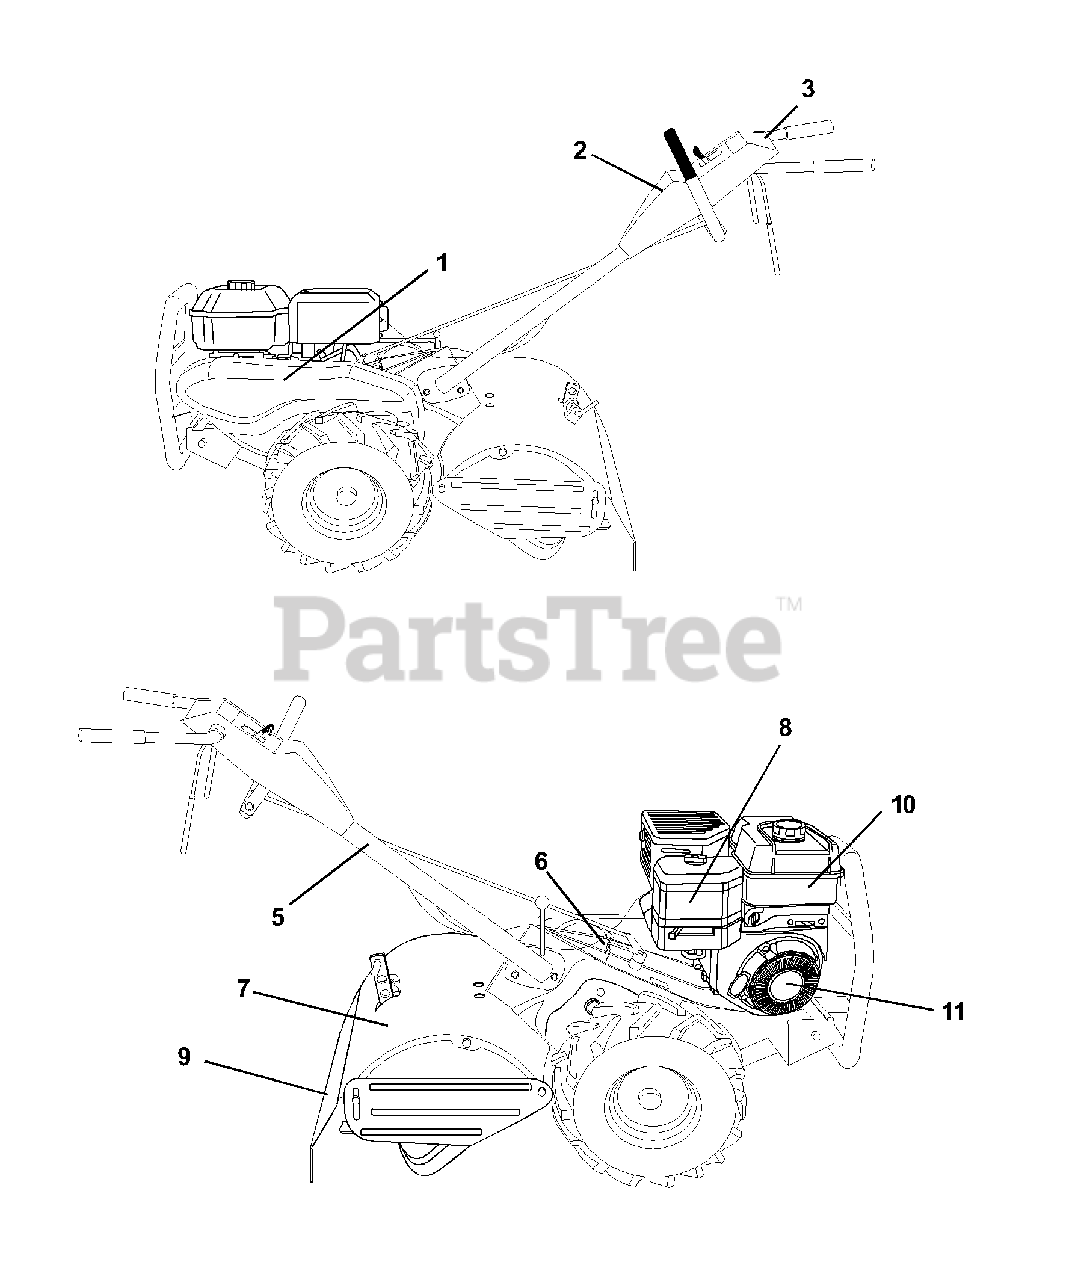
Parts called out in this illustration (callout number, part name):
1	Decal, Logo
2	Decal, Logo
3	Decal, Logo
5	Decal, Hand Placement
6	Decal, Shift Indicator
7	Decal, Warning
8	Decal, Engine HP
9	Decal, Warning, Rotating Tines
10	Decal, Engine Intek REF
11	Decal, Rewind Intek #274350
